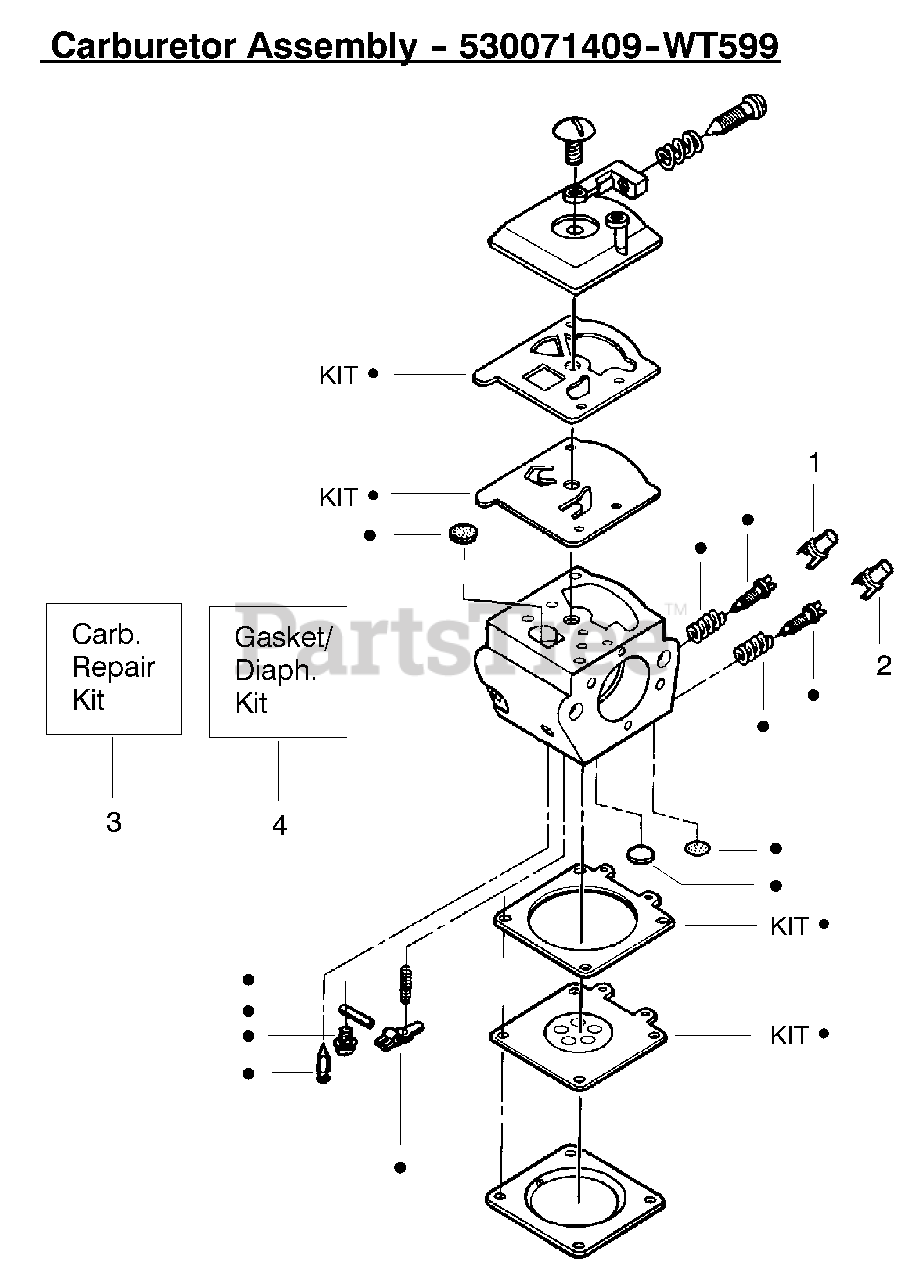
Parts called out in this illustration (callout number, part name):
1	Limiter Cap-High
2	Limiter Cap-Low
3	Carburetor Repair Kit
4	Gasket/Diaphragm Kit
